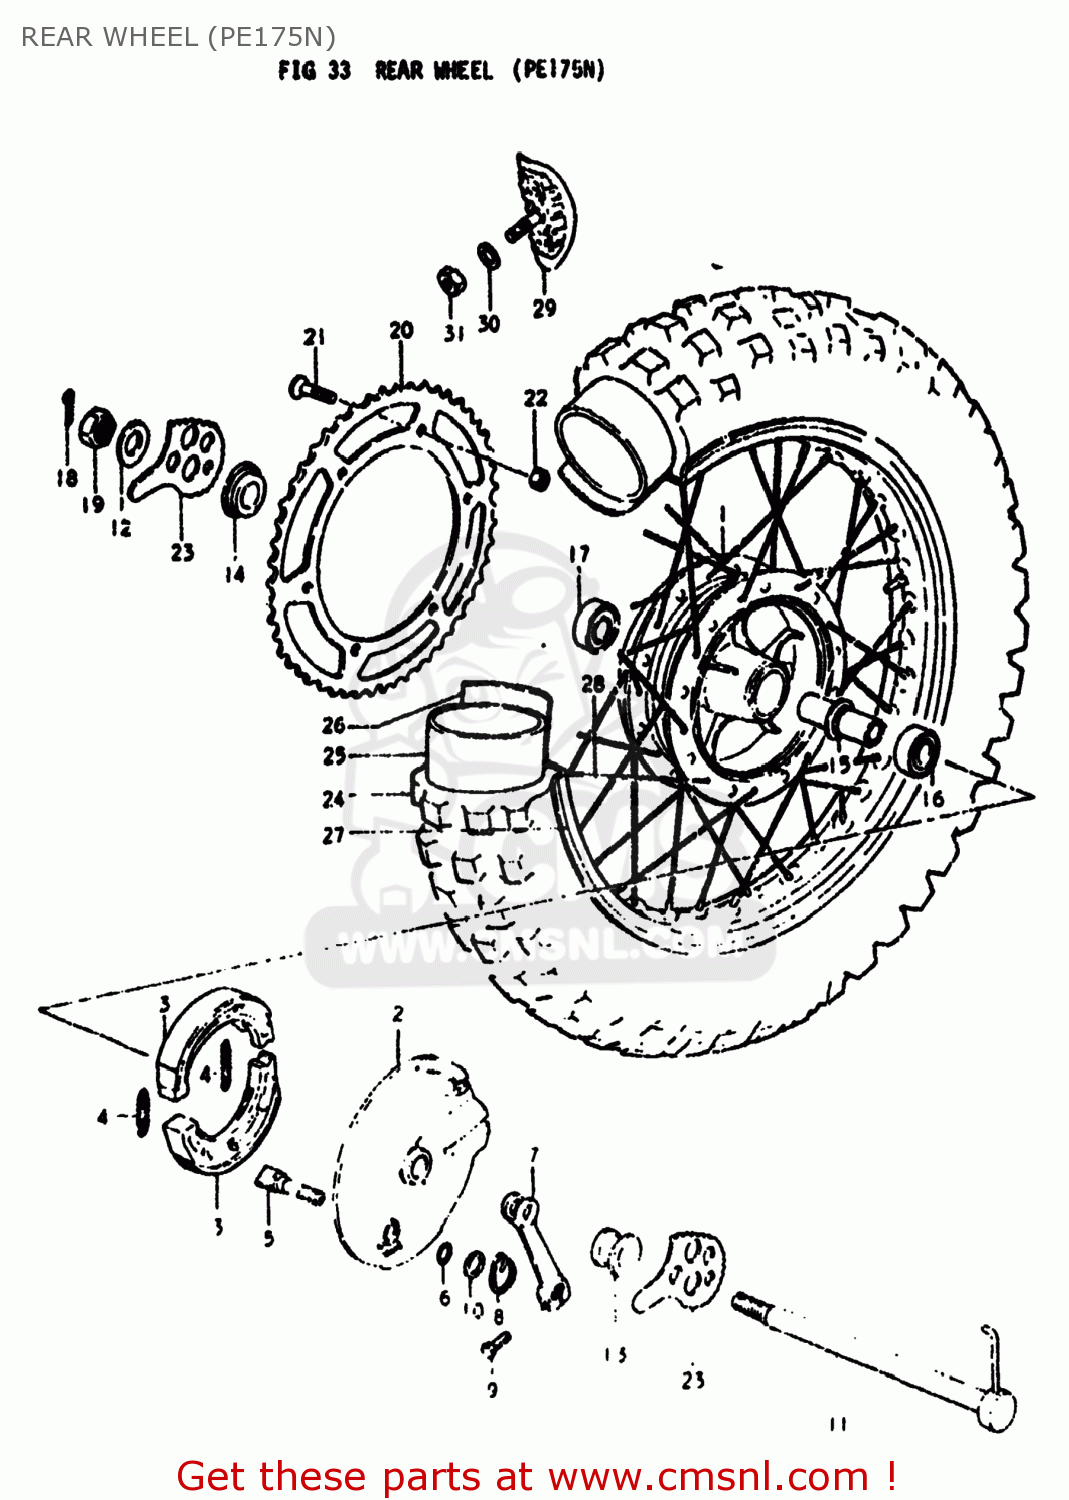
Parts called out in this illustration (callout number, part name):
1	HUB COMP,REAR
2	PANEL,REAR HUB
3	SHOE BRAKE (MCA)
4	SPRING(L:34)
5	CAM,FR BRAKE
6	O RING(D:2.5,ID:11.4)
7	LEVER,REAR BRAKE CAM
8	SPRING
9	BOLT
10	WASHER(12.5X20X1)
11	AXLE,REAR
12	WASHER
13	SPACER,REAR AXLE,RIGHT
14	SPACER,REAR AXLE
15	SPACER,RR WHEEL HUB BEARING
16	BEARING
17	BEARING
18	PIN 30X40
19	NUT
20	SPROCKET,REAR
21	SCREW
22	NUT
23	ADJUSTER,CHAIN
24	TIRE
25	TUBE ASSEMBLY,WHEEL,INNER
26	PROTECTOR,WHEEL,INNER
27	RIM,REAR WHEEL
28	SPOKE SET,REAR
29	STOPPER,BEAD
30	WASHER
31	NUT
